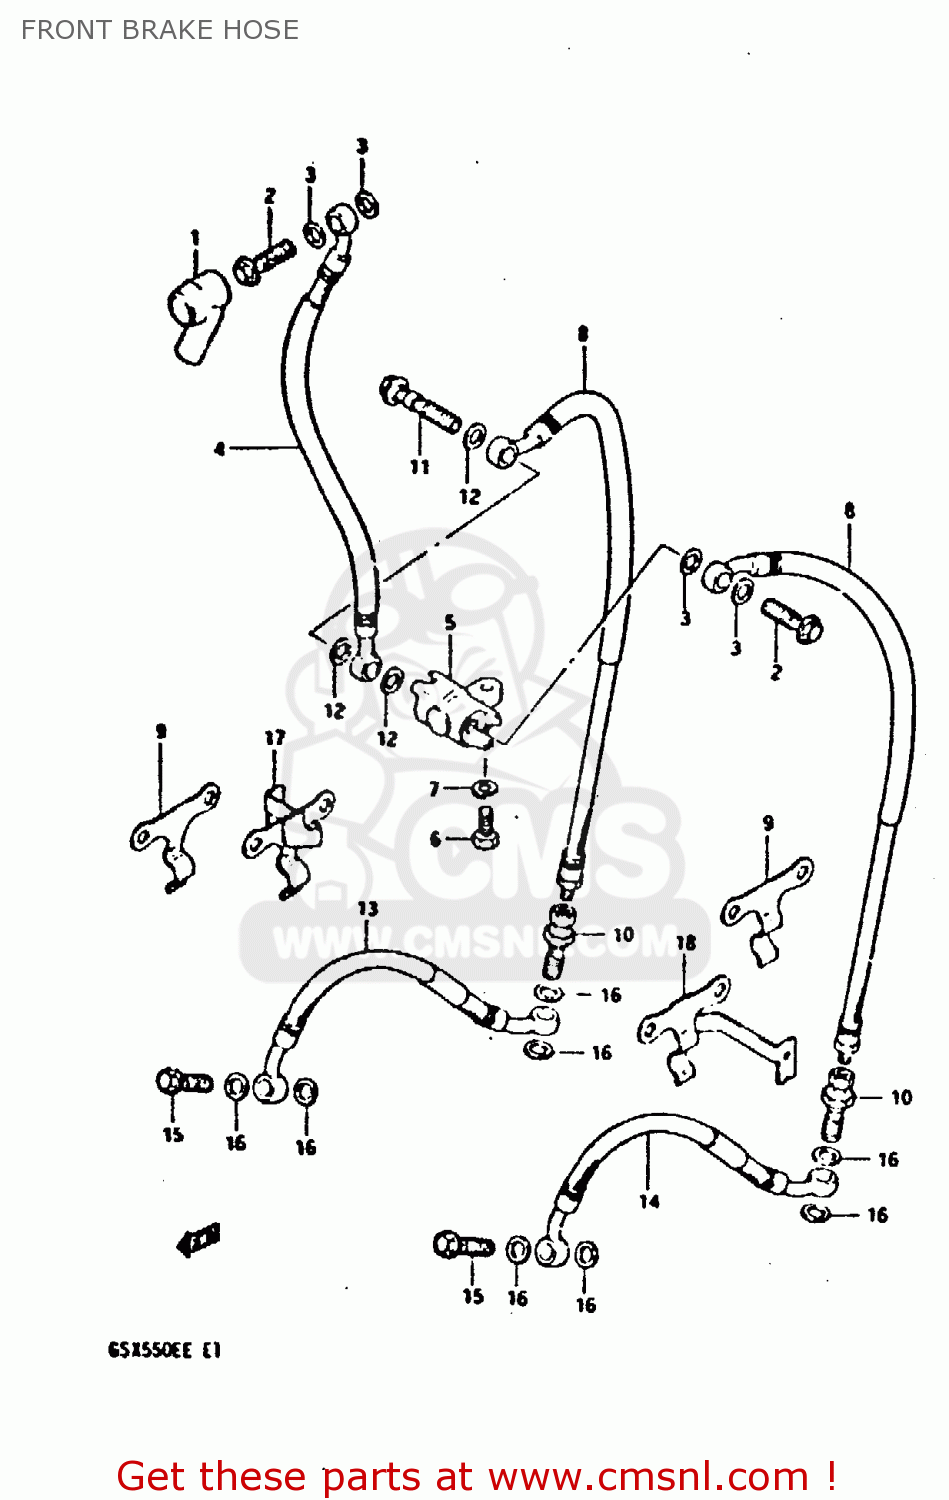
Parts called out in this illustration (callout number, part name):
1	BOOT,MASTER CYLINDER
2	BOLT UNION
3	WASHER
4	HOSE,FRONT BRAKE
5	JOINT,BRAKE HOSE
6	BOLT
7	LOCK WASHER
8	HOSE,BRAKE NO.2
9	CLAMP, HOSE
10	ADAPTER,BRAKE HOSE
11	BOLT,UNION
12	WASHER
13	HOSE,ANTI-NOSE DIVE,RIGHT
14	HOSE,ANTI-NOSE DIVE,LEFT
15	BOLT UNION
16	WASHER
